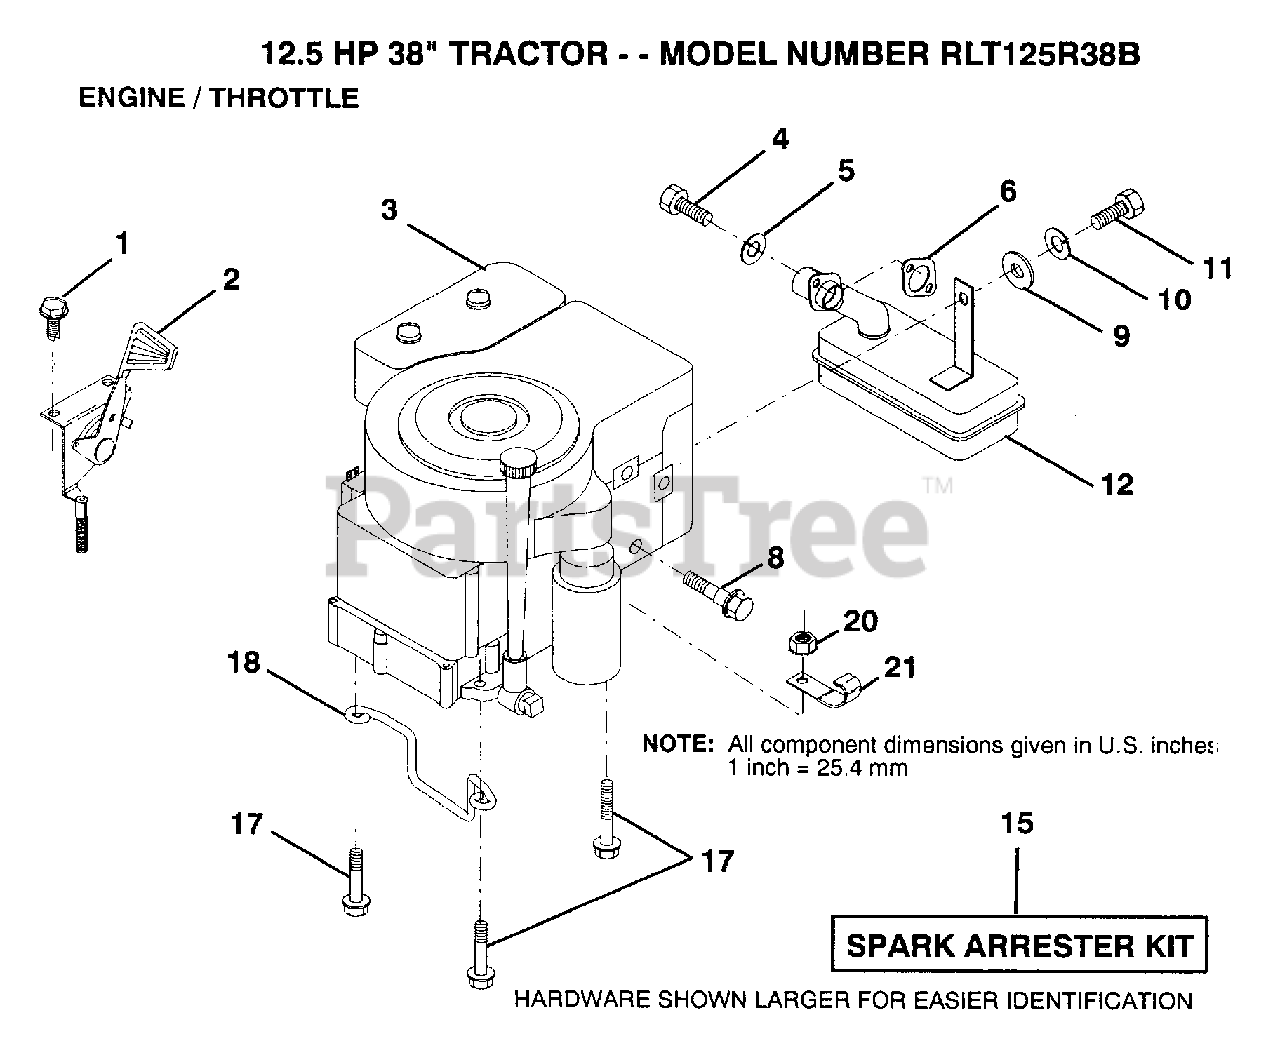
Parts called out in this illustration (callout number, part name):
1	SCREW.1/4-20X1/2
2	THROTTLE CONTROL
4	SCREW
5	LOCKWASHER
8	SHOULDER BOLT ST
10	LOCKWASHER
11	BOLT LT
17	SCREW LT
18	"KEEPER,DR BELT GR"
20	NUT
21	CLIP T
